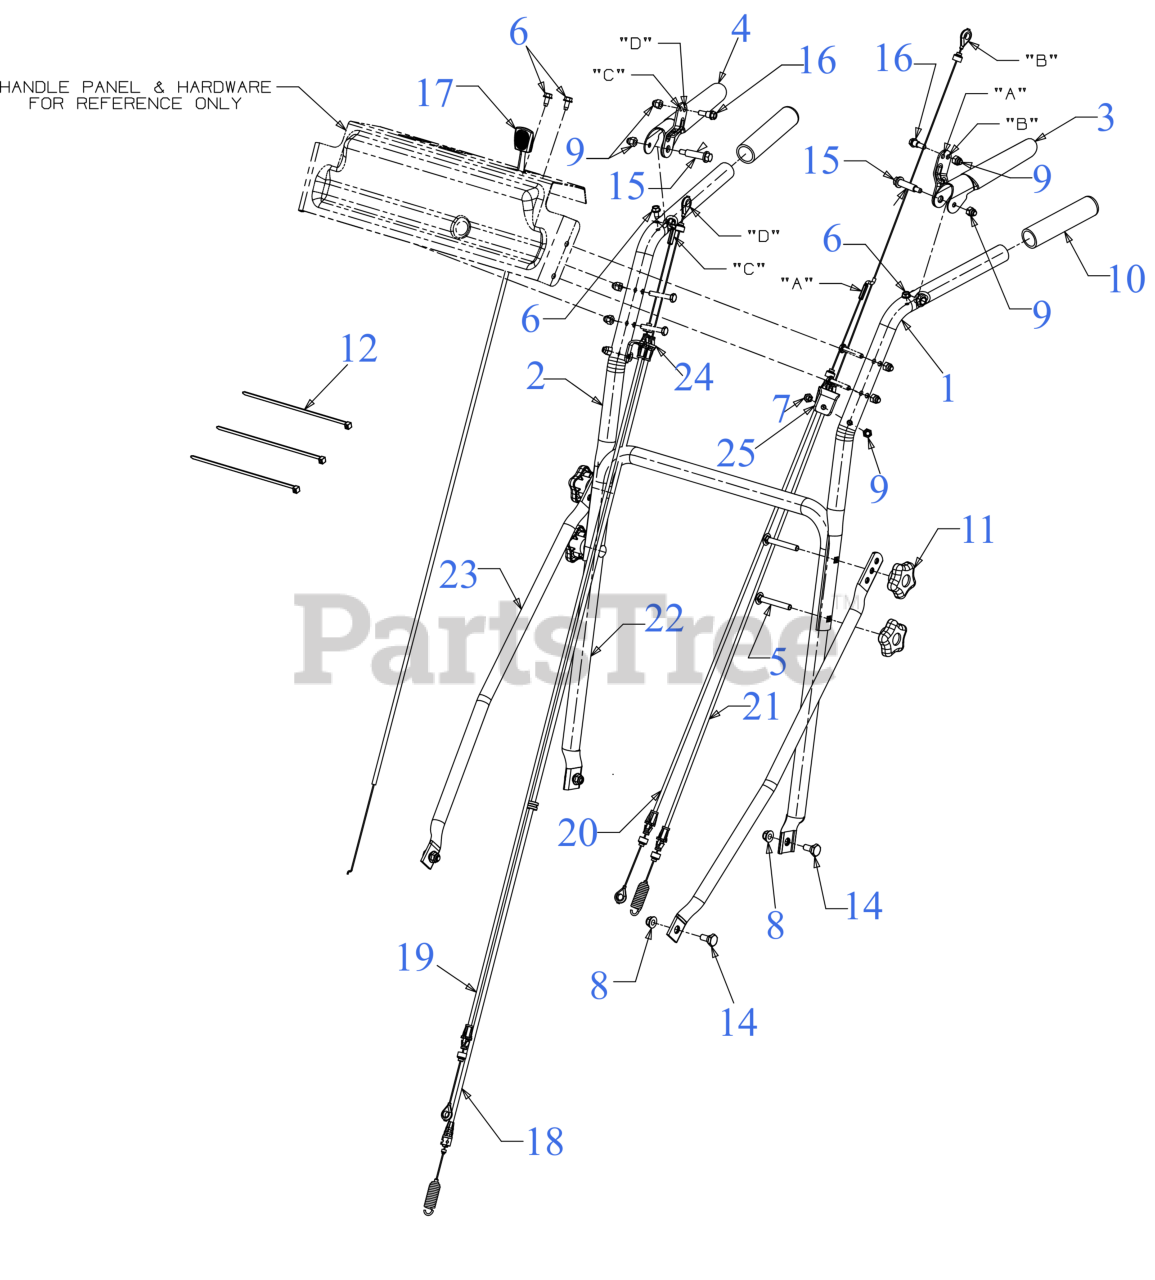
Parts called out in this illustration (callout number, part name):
3	LEVER ASSEMBLY (LH)
4	LEVER ASSEMBLY (RH)
5	BOLT 5/16-18 x 2.50 GR1
6	SCREW 1/4-20 X.500
7	SCREW 1/4-20 x 1.50 GR.5
8	FLANGE LOCK NUT 5/16-18
9	HEX ACORN NUT
11	STAR KNOB 5/16-18
12	7" CABLE TIE
14	SHOULDER SCREW .437
15	SHOULDER BOLT .375X1.285:1/4-20
16	SHOULDER SCREW .342X.335X1/4-20
17	THROTTLE/CHOKE CABLE 38" x 1.1
18	BLADE CONTROL CABLE
19	TRANSMISSION BRAKE CABLE (RH)
20	TRANSMISSION BRAKE CABLE (LH)
21	WHEEL CLUTCH CABLE
22	LOWER HANDLE (POWDER BLACK)
23	HANDLE ADJUSTMENT BRACE (POWDER BLACK)
24	CABLE BRACKET MOUNTING (RH)
25	CABLE BRACKET MOUNTING (LH)
